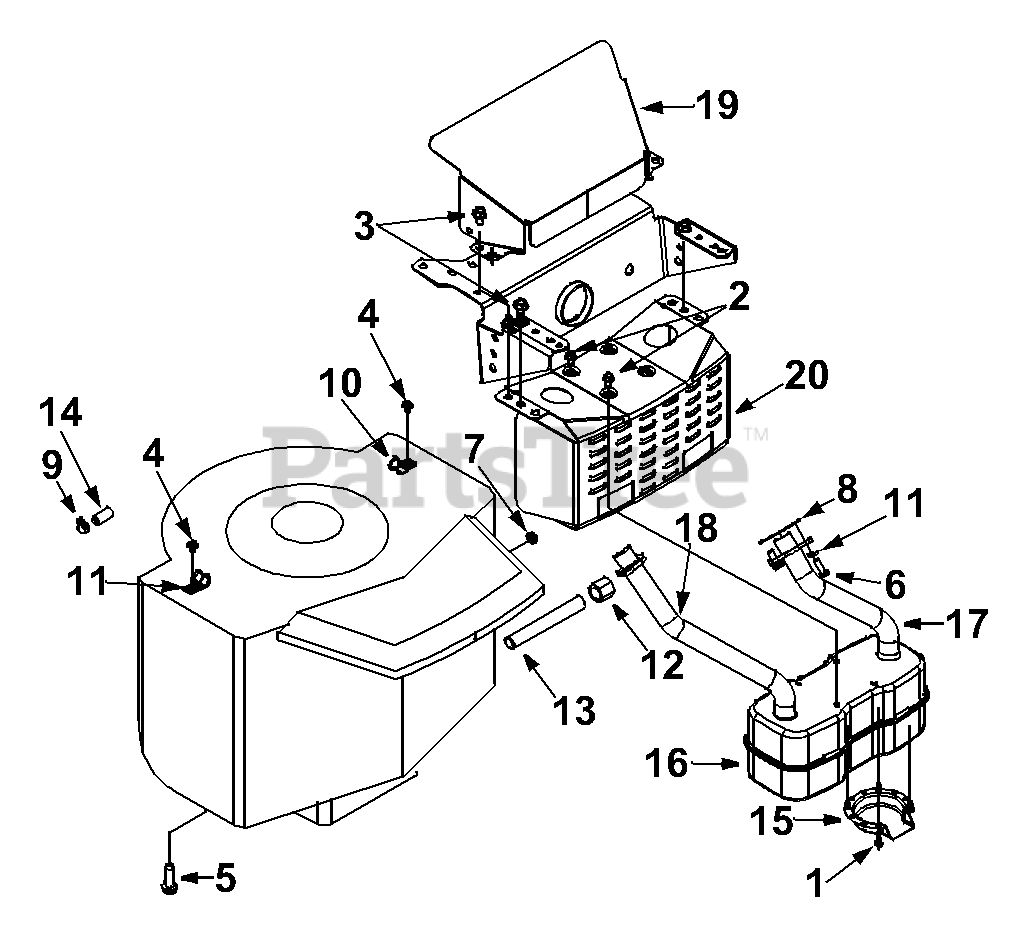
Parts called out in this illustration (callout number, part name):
1	Hex Tap Scr. #8-32 x .38" Lg.
2	Hex Wash. TT-Tap Scr. 1/4-20 x 5" Lg.
3	Hex Wash. TT-Tap Scr. 5/16-18 x .62" Lg.
4	Hex Hd. Tap Screw
5	Hex Hd. Tap Scr. 3.8-16 x 1.25" Lg.
6	Hex Bolt 1/4-20 x /75" Lg.
7	Hex Sems Nut 1/4-20 Thd.
8	Exhaust Gasket
9	Hose Clamp
10	Clamp
11	Lock Washer 1/4" I.D.
12	Oil Drain Cap
13	Pipe Nipple 3.8 x 18 NPT
14	Fuel Line Hose
15	Deflector: Muffler
16	Muffler
17	Exhaust Pipe - L.H.
18	Exhaust Pipe - R.H.
